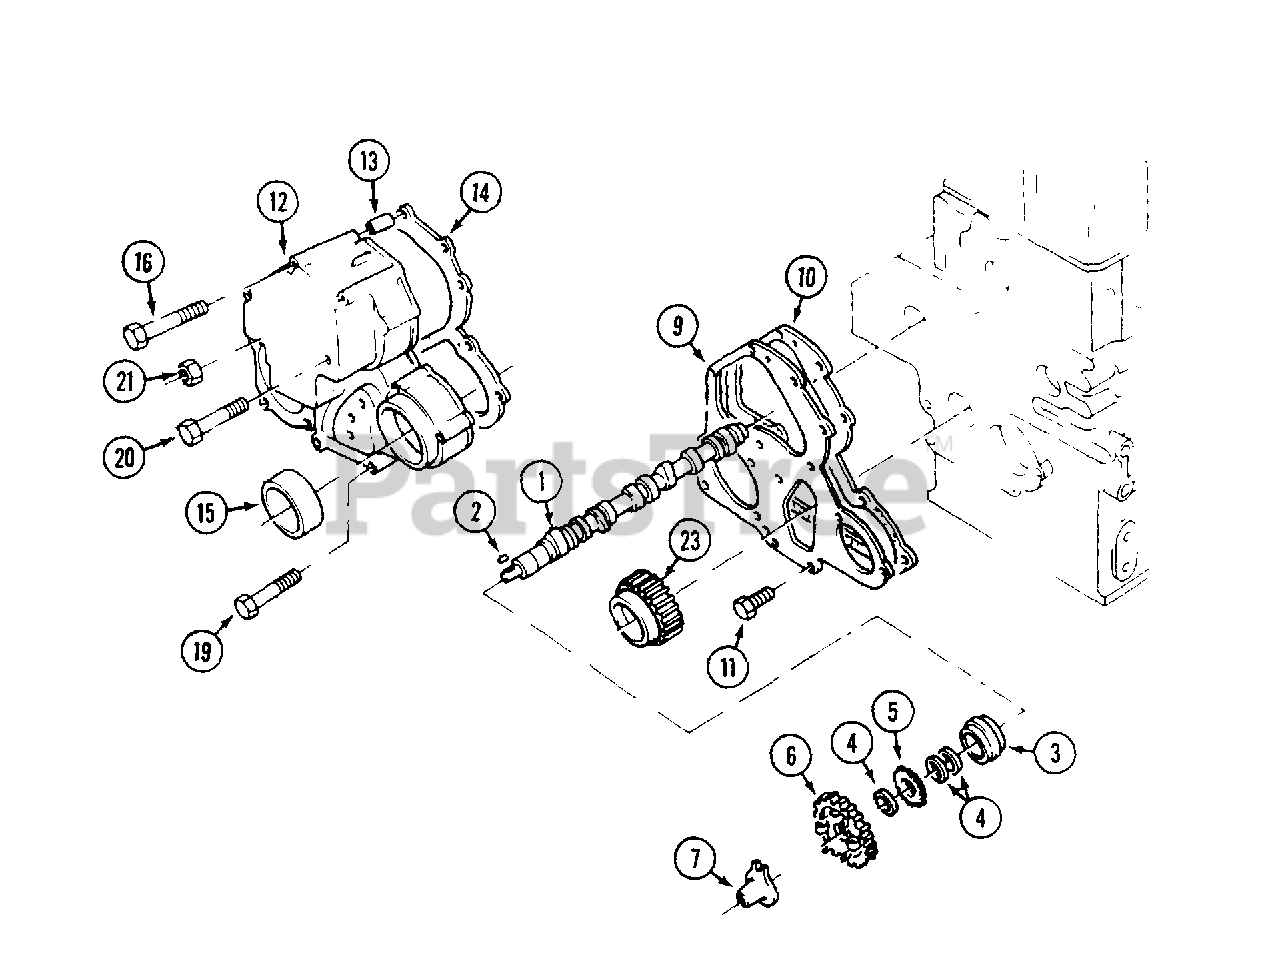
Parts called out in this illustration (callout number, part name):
1	CAMSHAFT
2	KEY
3	BEARING
4	SPACER
5	GEAR
6	GEAR
7	TAPPET
9	PLATE
10	GASKET
11	BOLT
12	CASE
13	PIN
14	GASKET
15	SEAL
16	SCREW
19	SCREW
20	SCREW
21	NUT
23	GEAR
